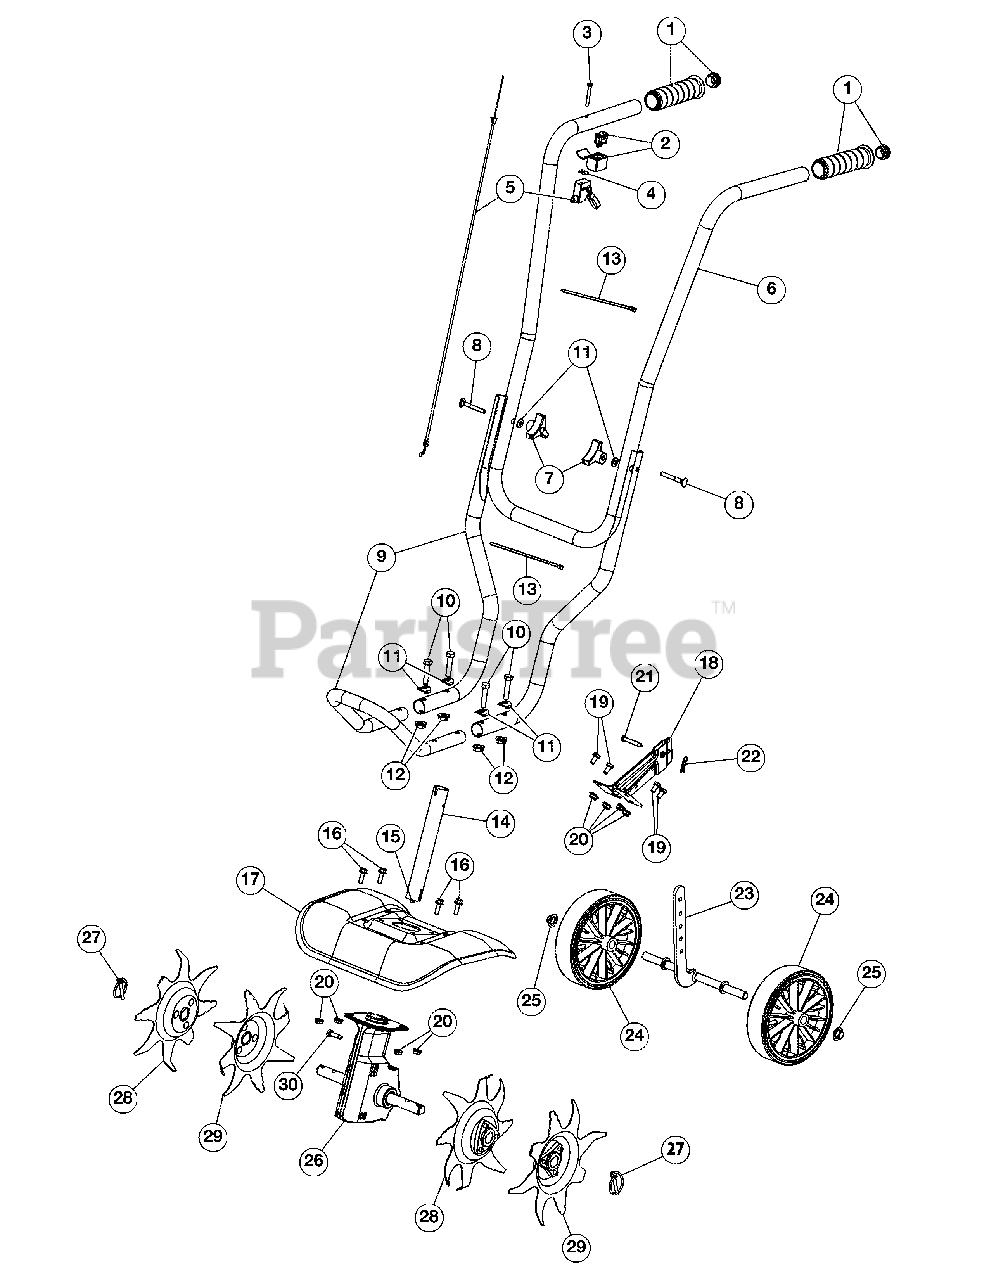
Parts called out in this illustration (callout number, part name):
2	Switch Assembly
3	Screw
4	Weld nut
5	Throttle Assembly
6	Upper Handle
9	Lower Handle Assembly
10	Bolt
11	Washer
12	Lock Nut
13	Cable Tie
14	Boom Assembly (Incl. 15)
15	Flex Shaft
16	Bolt
17	Tine Shield
18	Wheel Bracket Assembly
20	Lock Nut
21	Clevis Pin
22	Cotter Pin
23	Wheel Support Bracket
25	Push Cap
26	Gearbox
27	Click Pin
28	RH Outer/ LH Inner Tine
29	RH Inner/ LH Outer Tine
30	Bolt
